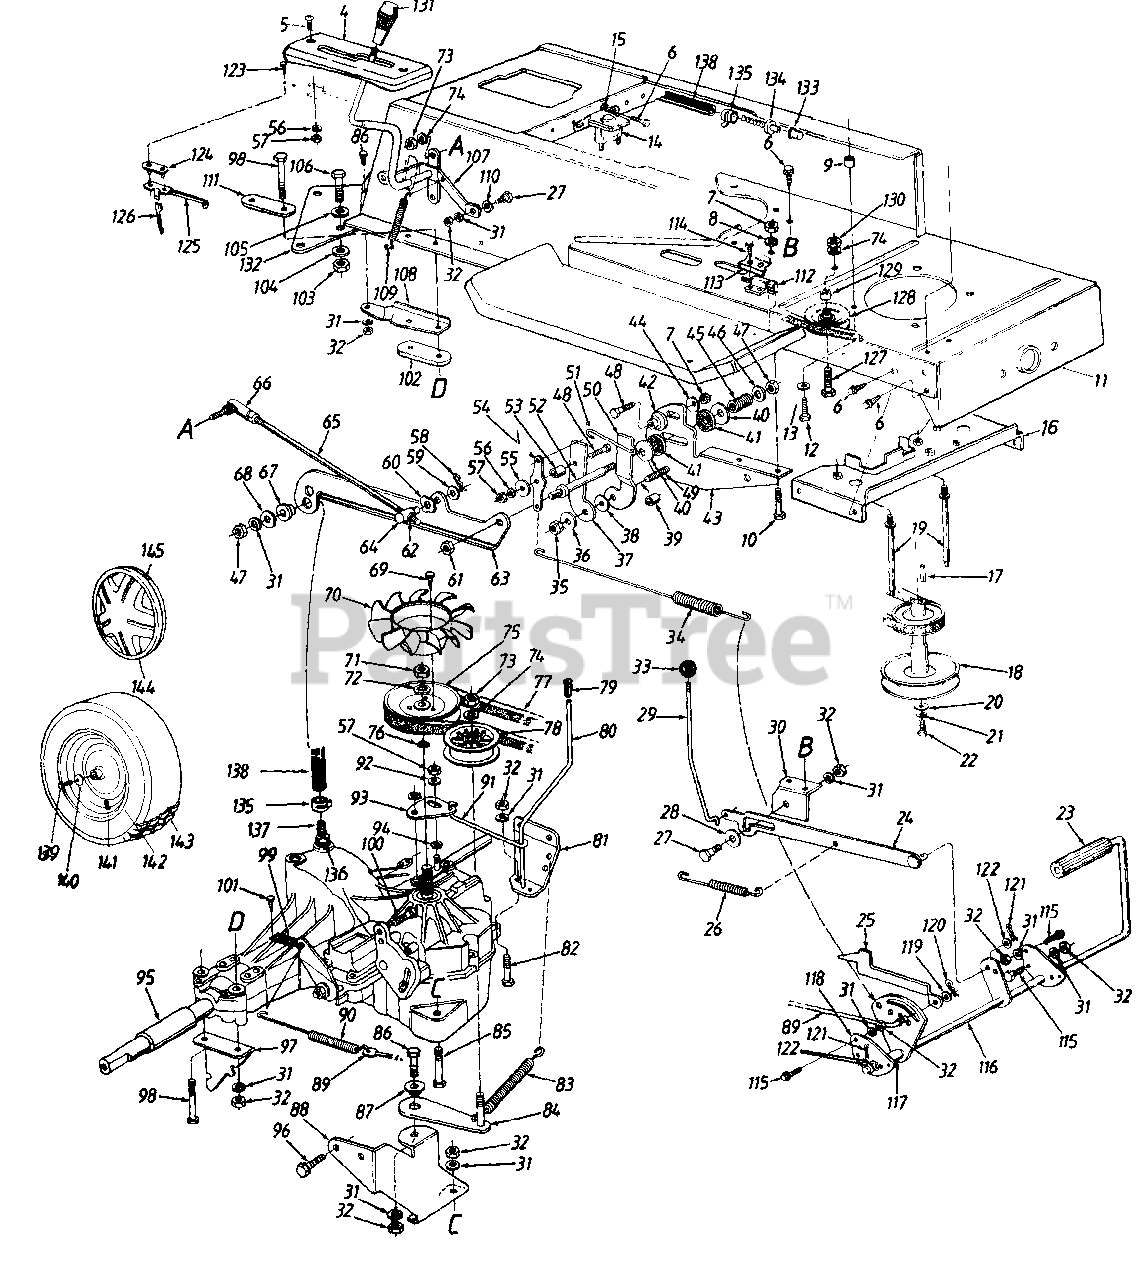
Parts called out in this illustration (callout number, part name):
4	Index Bracket
5	Pan Hd. Mach. Scr. 1/4-20 x .75" Lg.
6	Hex Wash. Hd. TT-Tap Scr. 1/4-20 x .5" Lg.
7	Hex Nut 1/4-28 Thd.
8	L-Wash. 1/4" I.D.
9	Shld. Spacer .38" I.D.
10	Hex . Bolt 1/4-28 x .62" Lg.
11	Lower Frame Ass'y.
12	Hex Tap Scr. 3/8-16 x 1.5" Lg.
13	Fl-Wash. .406" I.D. x 1.25"
14	Solenoid
15	Ext. L-Wash. 1/4" I.D.
16	Belt Guard Brkt. Ass'y.
17	Sq. Key 1/4" x 2" Lg.
18	Engine Pulley
19	Belt Guard Stud 3.6" Lg.
20	Fl-Wash. 7/16" I.D. x 1.25" O.D.
21	L-Wash. 7/16" I.D.
22	Hex Bolt 7/16-20 x 1.5" Lg.
23	Foot Pad
26	Foot Pedal Return Spring
27	Shld. Bolt .437" Dia. x .268"
28	Fl-Wash. 7/16" I.D. x 1-3/8" O.D.
29	Lock-up Rod
30	Bracket
31	L-Wash. 5/16" I.D.
32	Hex Nut 5/16-18 Thd.
33	Ball Knob
34	Neutral Return Spring
35	Hex Nut 5/16-24 Thd.
36	Fl-Wash. .344" I.D. x 1" O.D.
37	Scissor-Flat
38	Fl-Wash. .33" I.D. x 1.25" O.D.
39	Spacer
40	Bell-Wash. .4" I.D. x 1.13" O.D.
41	Friction Washer
42	Centering Gauge Spacer
43	Neutral Return Mtg. Brkt.
44	Bell-Wash. .265" I.D. x .75" O.D.
45	Comp. Spring 1.19" Lg.
46	Fl-Wash. .312" I.D. x .75" O.D.
47	Hex Nut 5/16-24 Thd.
48	Hex Bolt 1/4-28 x 1" Lg. (Gr. 5)
49	Rib Neck Bolt 5/16-24 x .84" Lg.
50	Scissor-Offset
51	Neutral Return Rod
52	Friction Disc Stud
53	Shld. Spacer
54	Neutral Return Lever
55	Fl-Wash. .265" I.D. x 1" O.D.
56	L-Wash. 1/4" I D.
57	Hex Nut 1/4-20 Thd.
58	Hairpin Clip
59	Fl-Wash .375" I.D. x .87" O.D.
60	Spring Wash. .39" I.D.
61	Hex L-Nut 3/8-24 Thd.
62	Hex Jam Nut 3/8-24 Thd.
63	Neutral Return Brkt.
64	Ferrule 3/8-24 Thd.
65	Control Rod
66	Ball Joint 3/8-24 Thd.
67	Shld. Spacer .5" Dia. x .27" Lg.
68	Fl-Wash. .349" I.D. x .879" O.D.
69	Hex Wash Hd. Tap Scr. #12 x 3/8" Lg.
70	Fan
71	Hex Nut 1/2-20 Thd
72	L-Wash. 1/2" I.D.
73	Hex Nut 3/8-24 Thd
74	L-Wash. 3/8" I.D.
75	Transmission Pulley
76	Wire Ring
77	"V"-Belt
78	Fl-Idler Pulley 2.75" O.D.
79	Rod End Grip
80	Bypass Control Lever
83	Ext. Spring 6.12
86	Hex Bolt 5/16-18 x .75" Lg.
87	Shld. Spacer 5" Dia. x .27" Lg.
90	Ext. Spring
91	Bypass Actuator Rod
92	Fl-Wash. .281" I.D. x .5" O.D.
93	Bypass Adjustment Brkt.
94	External L-Wash. 1/4" I.D.
95	Sleeve .758" I.D. x 1" O.D.
96	Hex . Wash TT - Tap Scr 5/16-18 x .62" Lg.
99	Tension Spring
100	Hex Bolt 5/16-24 x 1" Lg. (Special)
101	Hex Wash. Hd. AB-Tap Scr. #10 x 5" Lg.
102	Transaxle Spacer
103	Hex Nut 7/16-14 Thd. (Gr. 5)
104	Fl-Wash. .469" I.D. x .875" O.D.
105	Bell-Wash. .46" I.D. x 1.13" O.D.
106	Hex Bolt 7/16-14 x 1" Lg.
107	Speed Control Lever Ass'y.
110	Spr-Wash. .445" I.D. x .75" O.D.
112	Safety Switch (Clutch)
113	Switch Plate
114	Truss Mach. B-Tap Ser. #10 x .5" Lg.
115	Hex Wash. TT-Tap Scr. 5/16-18 x .75" Lg.
120	Cotter Pin 3/32" Dia.
121	Cotter Pin 1/8" Dia.
122	Fl-Wash. .64" I.D. x .94" O.D.
123	Hex Wash. Hd. AB-Tap Scr. #8 x .5" Lg.
124	Insulator Nut Plate
125	Reverse Safety Switch
126	Extension Wire
127	Mex Bolt 3/8-16 x 1.5" Lg. (14 H.P. OHV Only)
128	Idler Pulley (14 H.P. OHV Only)
129	Fl-Wash. .39" I.D. (14 H.P. OHV Only)
130	Hex Nut 3/8-16 Thd.
131	Shift Knob
132	Hitch Plate Extension
133	Vent Cap
134	Plastic Vent
135	Clamp
136	"O"-Ring
137	Hose Fltting
138	Fuel Line 18" Lg.
139	Hex Bolt 5/16-24 x .75" Lg.
140	Bell-Wash. .345" I.D. x .88" O.D.
141	Air Valve
142	Rim Only
143	Wheel Ass'y. Comp.
144	Hub Cap (Gray)
145	Spring Clip
